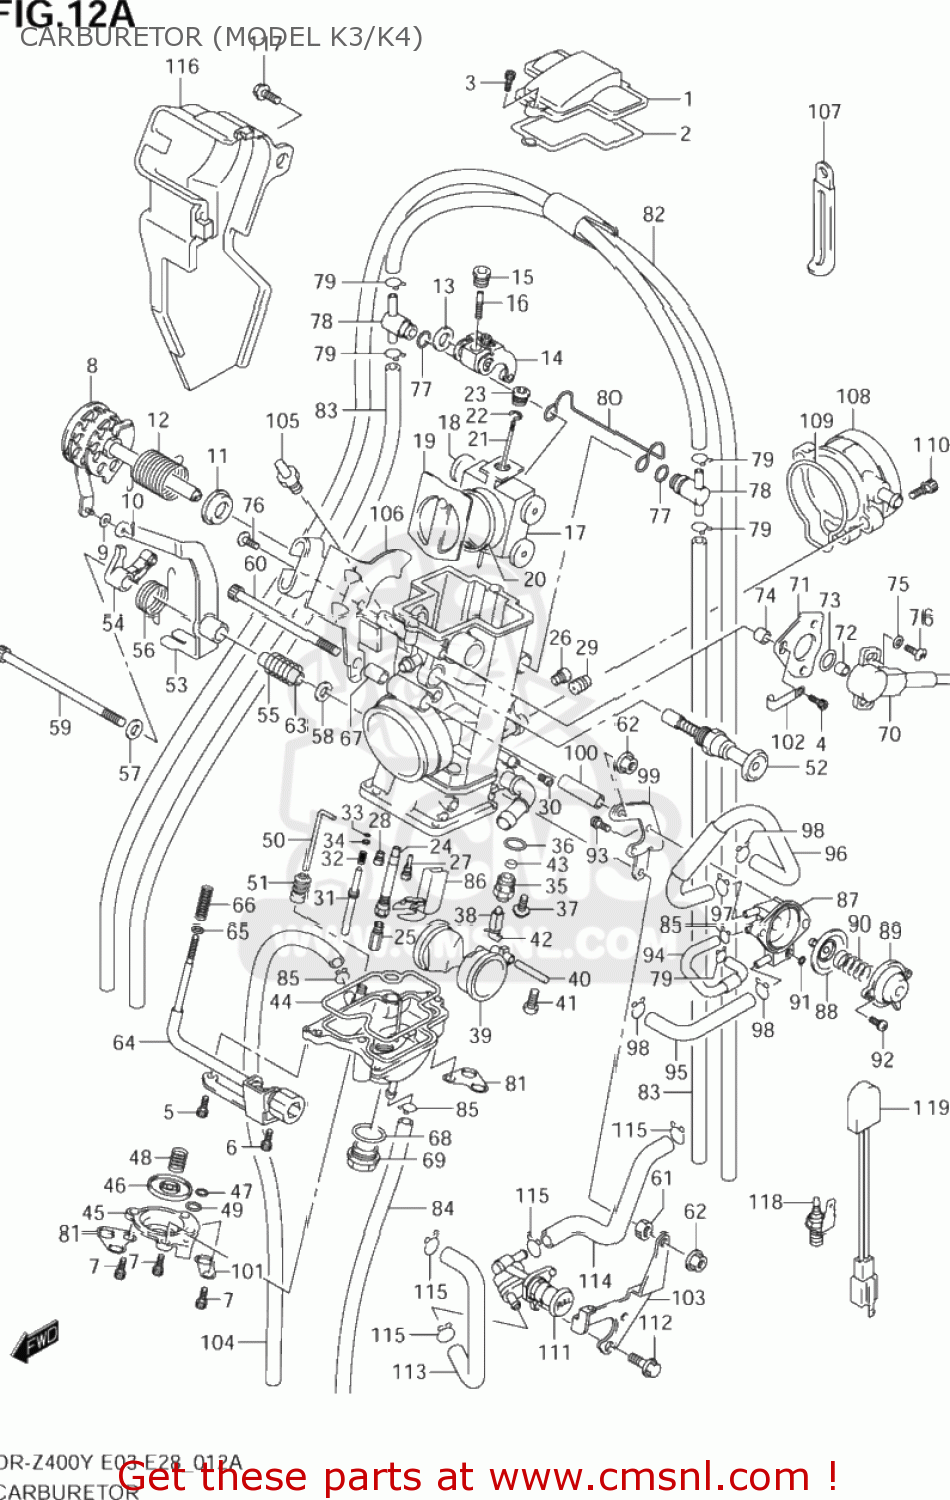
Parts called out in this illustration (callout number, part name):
1	2
2	TOP WASHER
3	4
4	5
5	6-1
6	7
7	BOLT(4X8)
8	SHAFT,THROTTLE
9	WASHER
10	PIN
11	COLLAR
12	SPRING
13	WASHER
14	15
15	16
16	SCREW
17	VALVE,THROTTLE
18	BEARING
19	VALVE
20	LIP SEAL
21	NEEDLE,JET
22	23
23	SCREW,NEEDLE SET
24	MAIN NOZZLE
25	JET,MAIN(142)
26	JET,MAIN AIR(200)
27	JET,SLOW(45)
28	JET,STARTER(65)
29	JET,SLOW AIR(60)
30	JET,AIR(90)
31	SCREW,ADJUST
32	SPRING
33	O RING
34	WASHER
35	VALVE SEAT
36	O RING
37	38
38	VALVE,FLOAT
39	FLOAT
40	41
41	42
42	CLIP
43	SCREEN,FUEL STRAINER
44	PACKING (NAS)
45	COVER
46	DIAPHRAGM
47	U RING
48	SPRING
49	O RING
50	ROD
51	CAP
52	53
53	54
54	LINK LEVER
55	SPRING
56	SPRING
57	WASHER
58	COLLAR
59	BOLT
60	BOLT
61	NUT
62	NUT
63	COLLAR
64	SCREW,STOP
65	66
66	67
67	COLLAR
68	69
69	BOLT
70	SENSOR,THROTTLE
71	PLATE
72	COLLAR
73	O RING
74	COLLAR
75	76
76	77
77	O RING
78	JOINT
79	80
80	CLIP
81	PLATE
82	PIPE
83	PIPE
84	PIPE,RUBBER
85	CLIP
86	PLATE
87	BODY,DIAPHRAGM
88	DIAPHRAGM
89	COVER
90	91
91	U RING
92	SCREW
93	SCREW
94	PIPE,RUBBER
95	PIPE,RUBBER
96	97
97	CLIP
98	99
99	PLATE,STAY
100	COLLAR
101	PLATE
102	BINDER
103	PLATE,STAY
104	PIPE
105	SCREW,STOP
106	PLATE STAY
107	CLAMP(L:65)
108	109
109	O RING,AIR CLNR JOINT
110	BOLT
111	112
112	BOLT
113	HOSE,STARTER TO HEAD
114	HOSE,STARTER TO AIR CLEANER
115	CLIP
116	COVER,CARBURETOR
117	BOLT
118	HEATER ASSY,CARBURETOR(15W)
119	THERMO SWITCH,CARB HEATER
